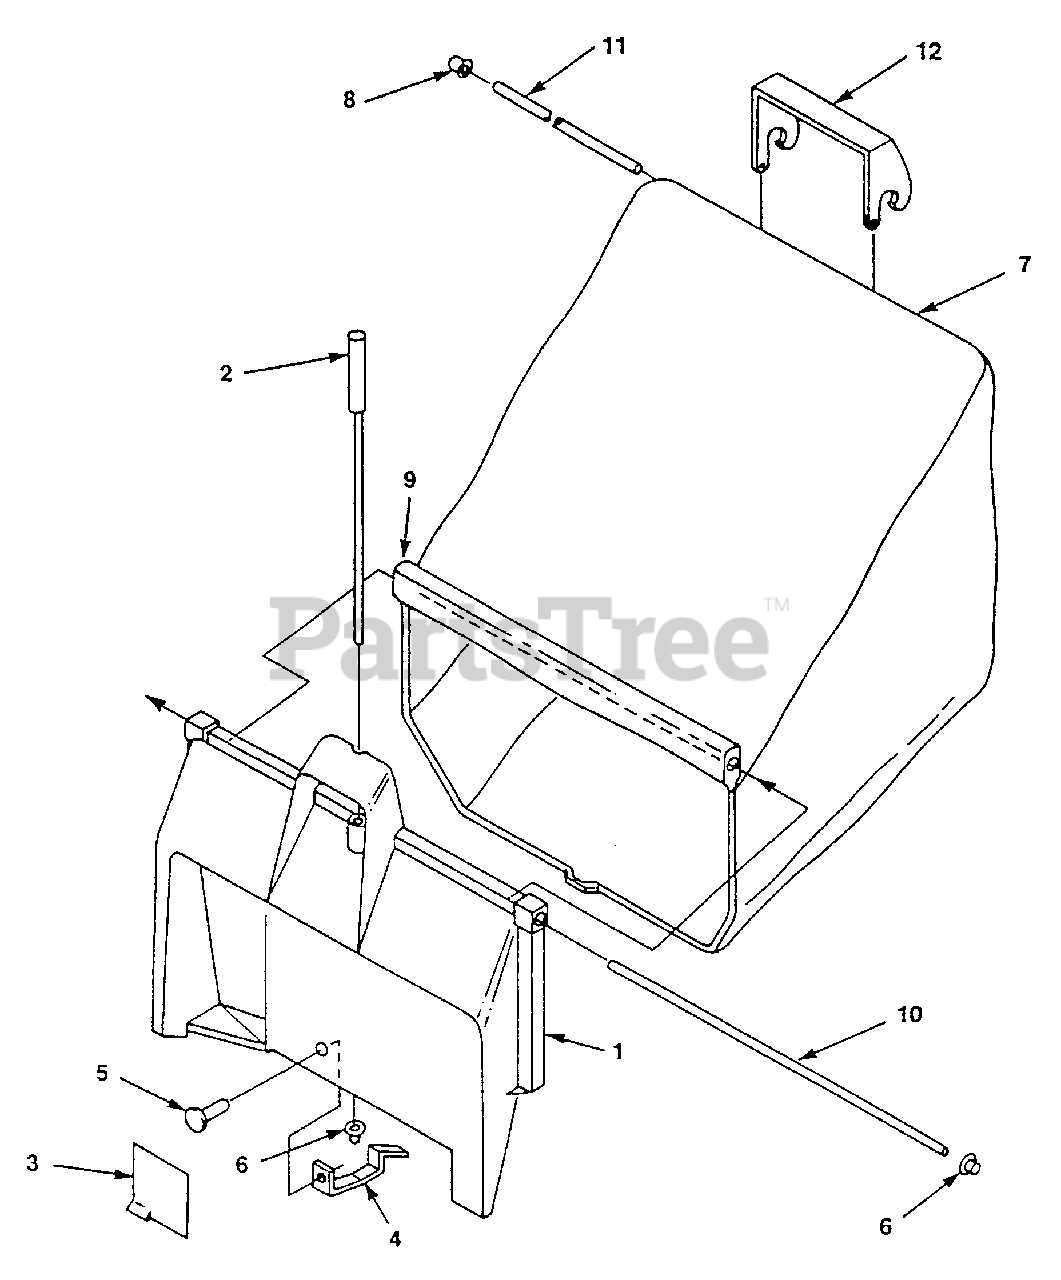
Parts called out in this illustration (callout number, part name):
1	ADAPTER ASSY.
2	ROD - Latch release
3	DEFLECTOR
5	RIVET 5/32 x 3/8"
6	NUT - Pal
7	BAG - Replacement
8	RETAINER - Bag rod
9	ROD - Bag support
10	ROD - Bag hinge
11	ROD - Bag
12	HANDLE - Bag
